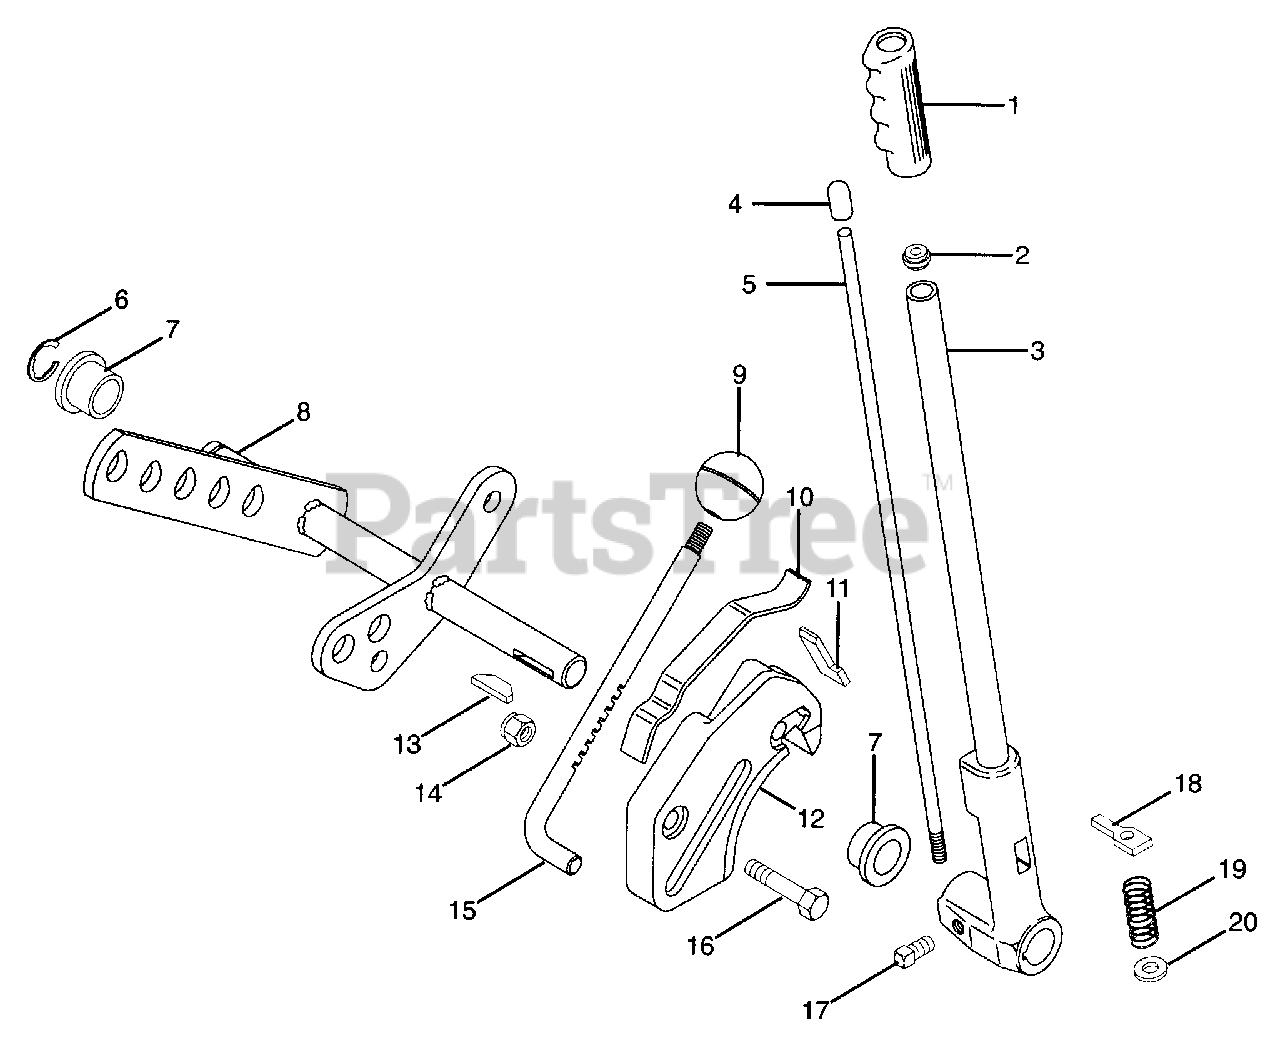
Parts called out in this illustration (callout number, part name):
1	Grip-Flex
2	Guide-Push Rod
3	Assembly-Lever Lift
4	Tip-Push Rod
5	Rod-Lever Push
6	Ring-Retaining-External .835 x .056
7	Bushing-Flange 1.020 x 1.385 x .75 x 1.75
8	Shaft-Lift Lever Weldment
9	Knob-Control .438-20 x .50
10	Spring-Stop
11	Stop-Lever
12	Casting-Locator
13	Key-Woodruff .25 x 2.13
14	Nut-Locking-Center .375-16 Grade 2
15	Rod-Lever Stop
16	Bolt-Hex .38-16 x 1.25 Grade 5
17	Screw-Set .38-16 x .50
18	Pawl-Lever
19	Spring-Compression .067 x .72 x 2.0
20	Washer-Flat-Steel .438 x 1.00 x .83
